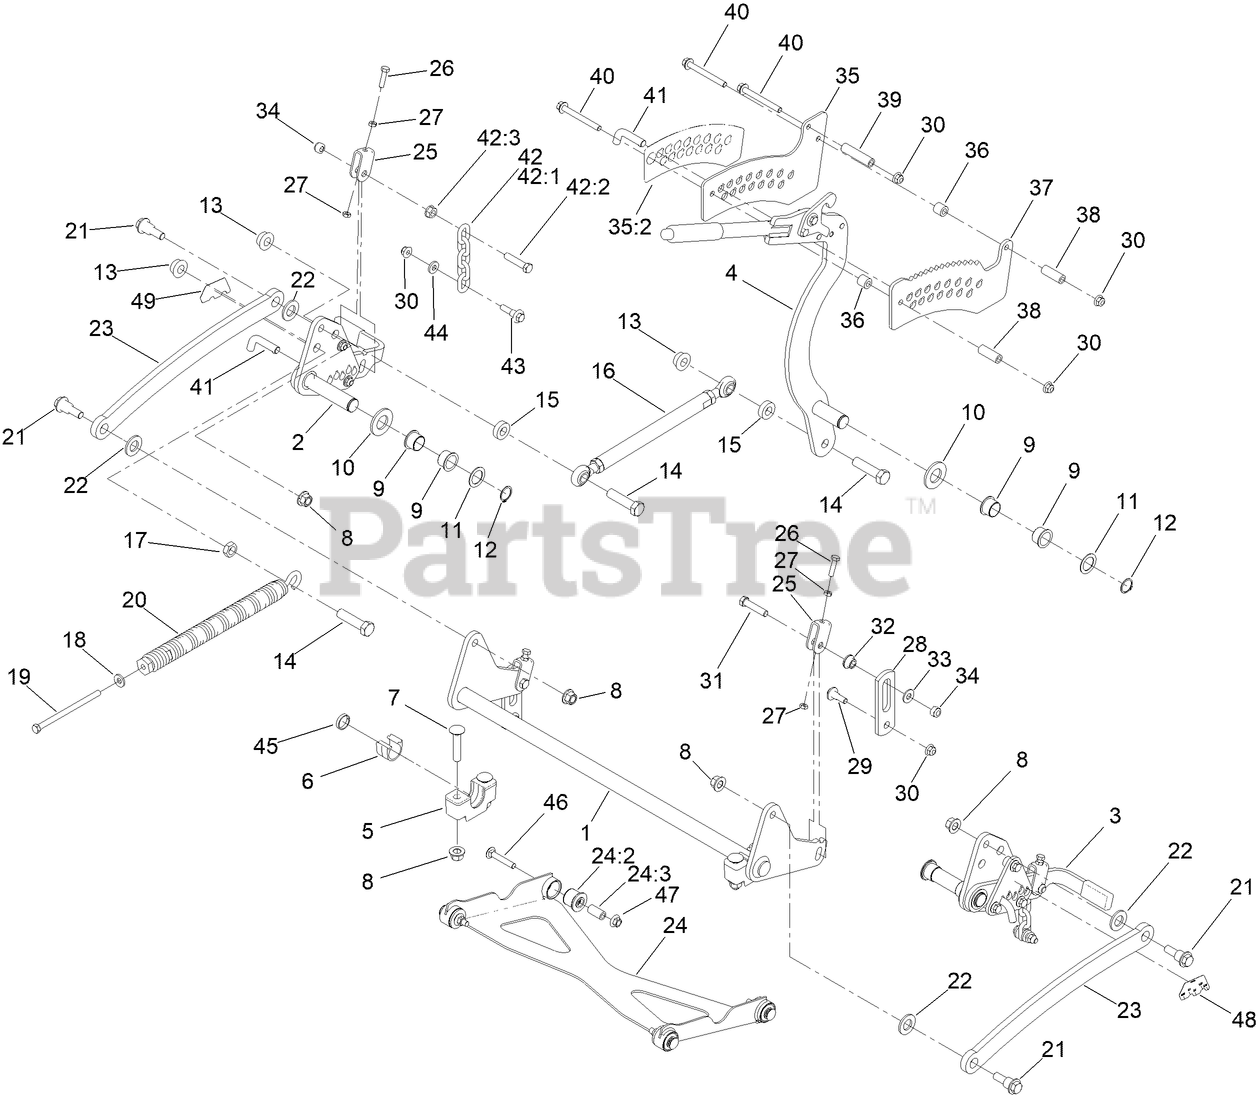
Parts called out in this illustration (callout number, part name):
1	SHAFT-CROSS, FRONT
2	PIVOT ASM, HOC
3	PIVOT ASM, HOC
4	HOC LEVER ASM
5	SUPPORT-CROSS SHAFT, BEARING
6	BEARING-CROSS SHAFT, FRONT
7	BOLT-CARR
8	NUT-LOCK
9	BUSHING
10	WASHER-FLAT
11	WASHER-THRUST
12	RING-RETAINING
13	NUT-HEX FLG
14	SCREW-LOCK
15	WASHER
16	HOC LINK ASM
17	NUT-JAM
18	WASHER-BELLEVILLE
19	BOLT-TAP, HH
20	SPRING-EXTENSION
21	SCREW-SHOULDER, HHF
22	WASHER-FLAT
23	LINK-LIFT
24	DECK STRUT ASM
24:2	BUSHING-RUBBER
24:3	SPACER
25	YOKE-ADJUST, DECK
26	SCREW-HH
27	NUT-JAM
28	LINK-LIFT
29	SCREW-SHOULDER, HHF
30	NUT-HF, NI
31	SCREW-HH
32	BUSHING-FLANGED
33	WASHER-FLAT
34	NUT-LOCK, NI
35	HOC PLATE AND DECAL ASM
35:2	DECAL-HOC
36	SPACER
37	PLATE-HOC, INNER
38	SPACER
39	SPACER
40	SCREW-HHF
41	PIN-HOC
42	DECK LIFT CHAIN ASM
42:1	CHAIN-LIFT, DECK
42:2	SCREW-HH
42:3	NUT-HF
43	BOLT-SHOULDER
44	SPACER
45	SPACER-SPLIT
46	SCREW-CARR
47	NUT-HF
48	DECAL-DECK RAKE, LH
49	DECAL-DECK RAKE, RH
